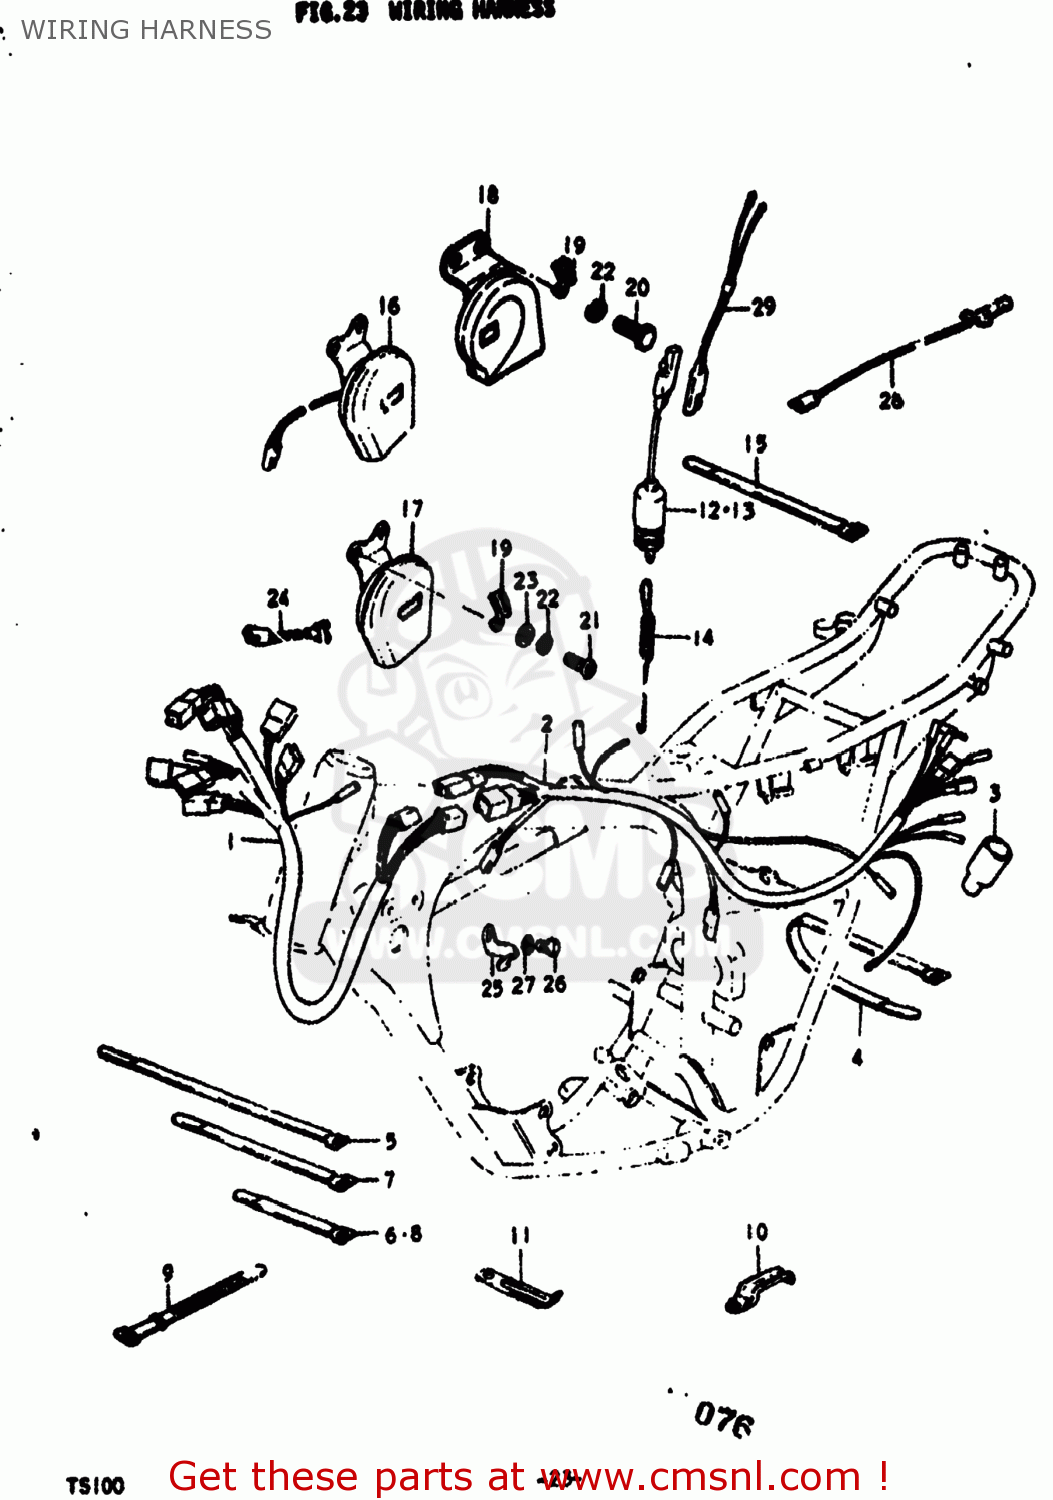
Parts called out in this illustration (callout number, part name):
1	HARNESS,WIRING
2	HARNESS,WIRING NO.2
3	COVER,WIRING HARNESS
4	CLAMP(L:250)
5	CLAMP
6	CLAMP
7	CLAMP
8	CLAMP
9	CLAMP(L:120)
10	CLAMP
11	CLAMP
12	SWITCH ASSEMBLY,STOP LAMP
13	SWITCH ASSY,BRAKE LAMP
14	SPRING
15	CLAMP
16	HORN ASSEMBLY
17	HORN ASSEMBLY
18	HORN ASSY
19	CLAMP
20	BOLT
21	SCREW 6X12
22	LOCK WASHER
23	WASHER
24	WIRE
25	CLIP,BRAKE CABLE
26	BOLT
27	LOCK WASHER
28	WIRE,WIRING HARNESS LEAD
29	WIRE
